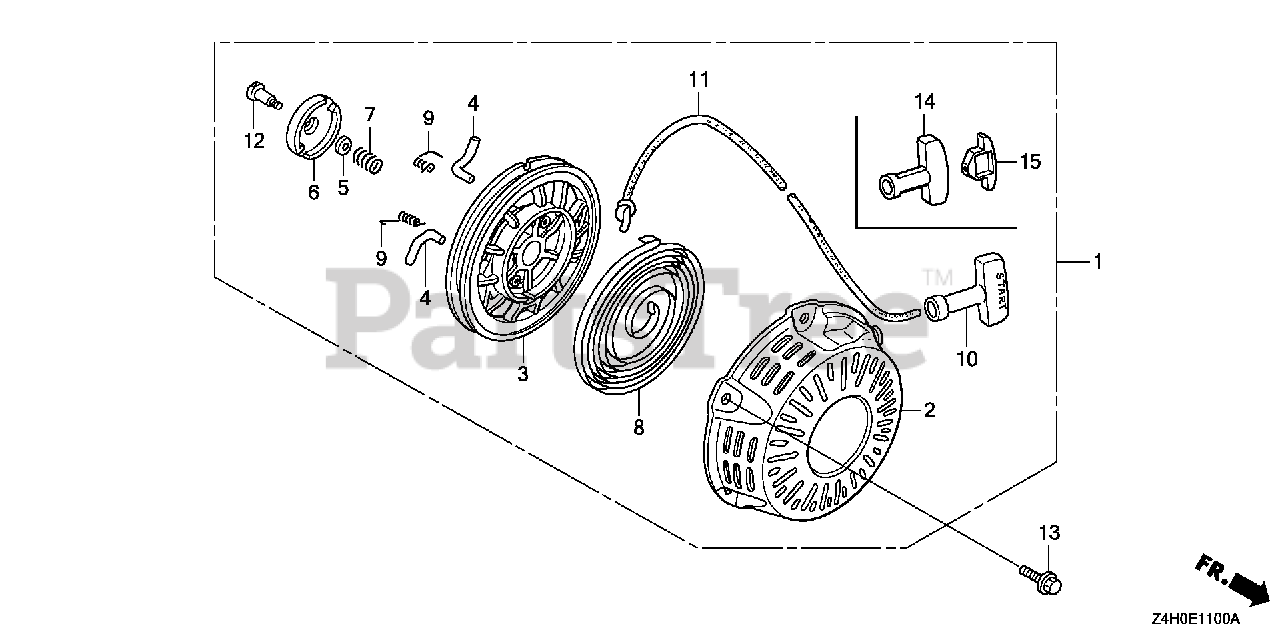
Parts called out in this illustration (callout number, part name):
1	STARTER ASSY., RECOIL *R280* (COO)(FOR U.S.A.) (POWER RED)
2	CASE, RECOIL STARTER *R280* (POWER RED)
3	REEL, RECOIL STARTER
4	RATCHET, STARTER
5	PLATE, FRICTION
6	GUIDE, RATCHET
7	SPRING, FRICTION
8	SPRING, RECOIL STARTER
9	SPRING, RETURN
11	ROPE, RECOIL STARTER
12	SCREW, SETTING
13	BOLT, FLANGE (6X10)
14	KNOB, RECOIL STARTER (COO)(FOR U.S.A.)
15	KNOB, REINFORCEMENT
